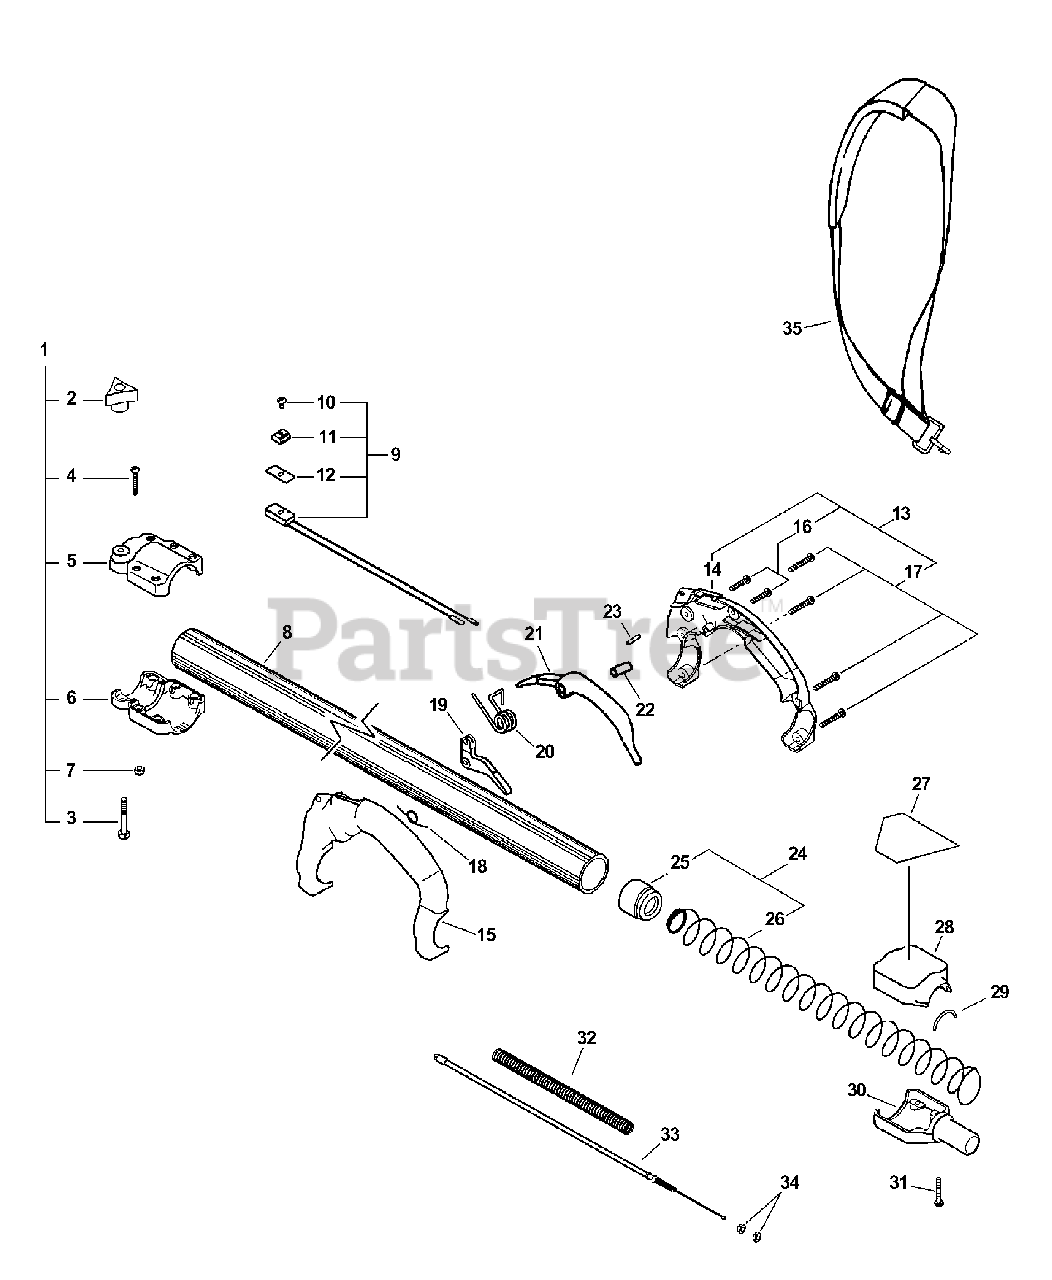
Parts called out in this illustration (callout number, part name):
1	COLLAR ASSY
2	THUMBSCREW
3	SCREW - 1/4-20 X 1-3/4"
4	SCREW - 10-24 X 1-1/4"
5	COLLAR, MAIN PIPE - UPPER
6	COLLAR, MAIN PIPE - LOWER
7	LOCKNUT - 10-24
8	PIPE, MAIN - ORANGE
9	IGNITION SWITCH ASSY
10	SCREW - 3X10
11	KNOB, SWITCH - ORANGE
12	COVER, SWITCH - STOP
13	HANDLE ASSY - REAR
14	HANDLE, REAR - RIGHT
15	HANDLE, REAR - LEFT
16	SCREW - 10-24 X 7/8"
17	SCREW - 10-24 X 1-1/4"
18	SPRING, TRIGGER
19	TRIGGER, THROTTLE
20	SPRING, LOCKOUT LEVER
21	LOCKOUT, THROTTLE
22	COLLAR - 5
23	PIN - LOCATING
24	FLOATING BUSHING ASSY
25	BUSHING, FLOATING
27	LABEL - CAUTION
28	LOWER HSNG ADAPT (TOP)
30	ADAPTER, LOWER SHAFT TUBE
31	SCREW - 10-24 X 1-1/4"
32	TUBE, PROTECTIVE - CORRUGATED
33	CABLE, THROTTLE
35	SHOULDER STRAP ASSY
